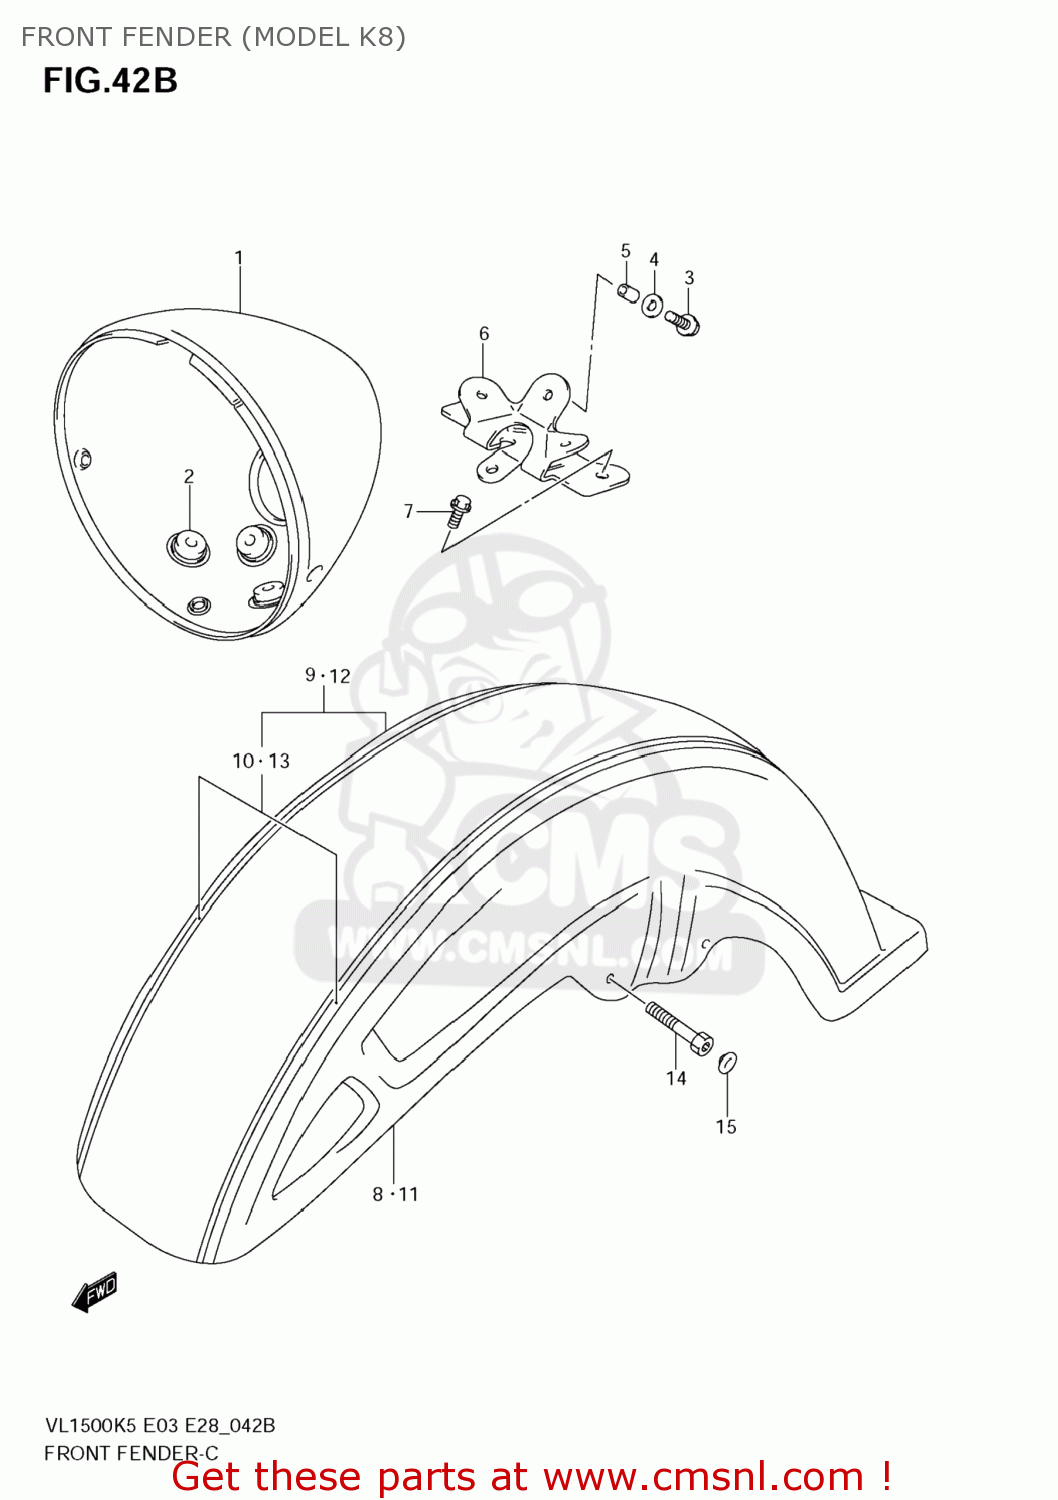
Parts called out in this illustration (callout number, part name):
1	HOUSING ASSY,HEADLAMP
2	CUSHION
3	BOLT
4	WASHER(6.5X20X1.2)
5	SPACER(6.5X9X10)
6	BRACKET,HEADLAMP HOUSING
7	BOLT
8	FENDER,FR
9	FENDER ASSY,FR
10	TAPE SET,FR FENDER
11	FENDER,FR
12	FENDER ASSY,FR
13	TAPE SET,FR FENDER
14	BOLT
15	CAP(OD:11)
